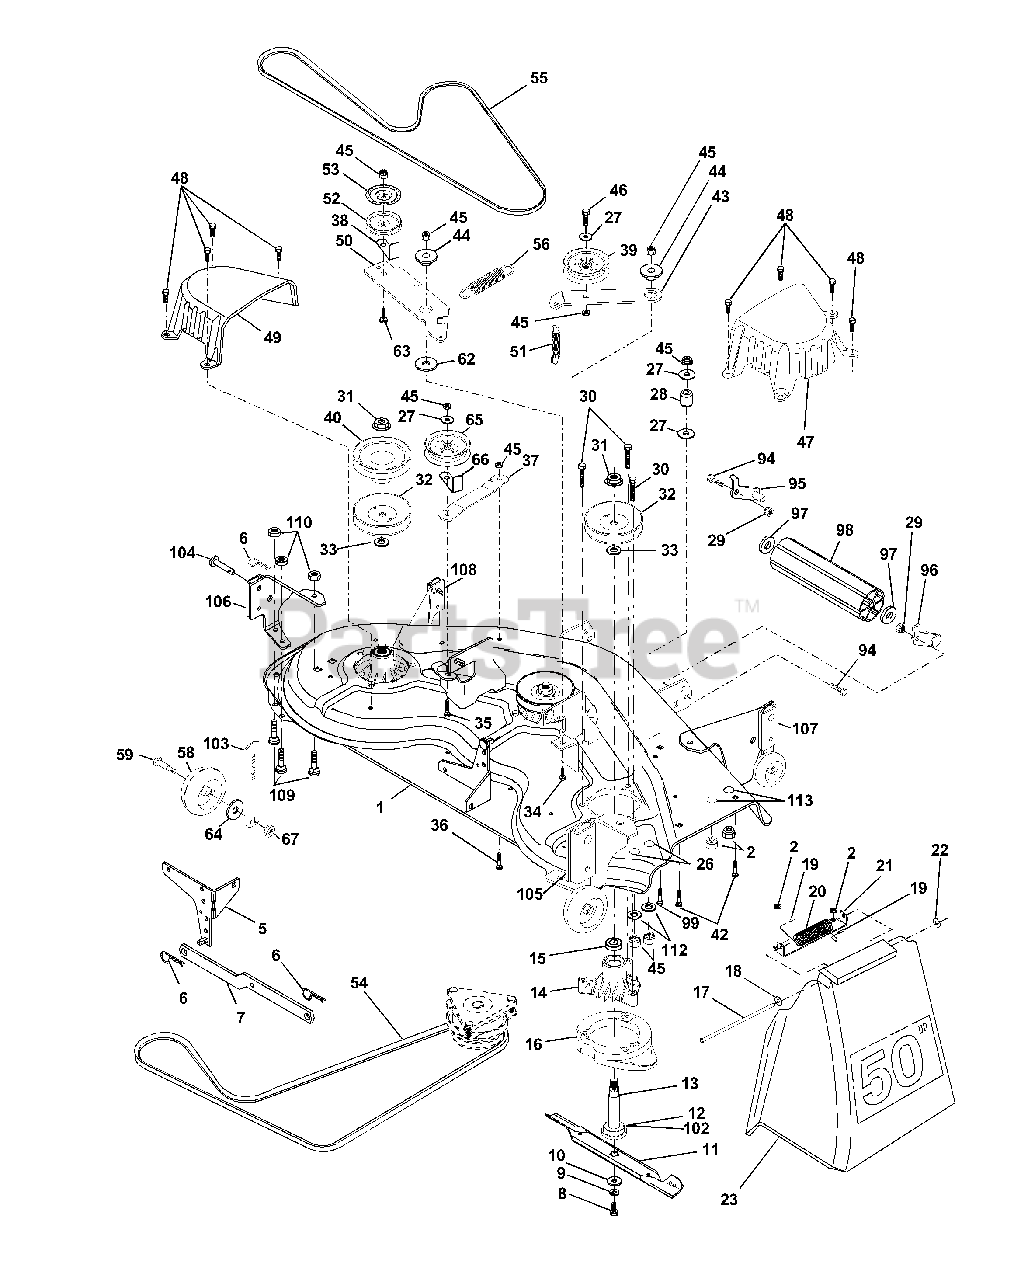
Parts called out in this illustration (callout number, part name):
1	Deck Asm., Mower 50"
2	Nut, Crownlock 5/16-18
5	Bracket Asm., Sway Bar
6	Retainer, Spring
7	Arm Suspension, Rear
8	Bolt 3/8-24 x 1.25 Gr. 8 Patched
9	Washer, Lock Hvy 3/8 Unplated
10	Washer, Hard Blade Mower Vented
11	Blade (3 Required)
12	Bearing, Ball #6204 (Mandrel)
13	Shaft Asm., W/Lower Brg
14	Housing, Mandrel 50" Vent
15	Bearing, Ball Mandrel
16	Stripper, Mower Vented
17	Rod, Hinge
18	Washer 11/32 x 5/8 x 16 Ga.
19	Cap Sleeve
20	Spring, Torison Delector
21	Bracket, Deflector
22	Nut, Push
23	Shield, Deflector Mower
25	Washer 11/32 x 3/4 x 16 Ga.
26	Bolt Rd Hd Sht Sqnk
27	Washer 13/32 x 13/16 x 16 Ga.
28	Spacer, Spring Stop Idler
29	Nut, Lock Hex W/Wsh 3/8-16 Unc
30	Screw Thd Rolling Washer Head
31	Nut, Flg Top Lock Cntr 9/16
32	Pulley, Mandrel
33	Washer, Spacer Mower Vented
34	Bolt, Carriage 3/8-16 x 1-1/4
35	Bolt, Carriage 3/8-16 x 2
36	Bolt, Carriage 3/8-16 x 1 Gr. 5
37	Stiffener, Arm Idler
38	Keeper, Belt Idler
39	Pulley, Idler Flat
40	Pulley, Driven
42	Bolt, Carriage 5/16-18 Unc x 3/4
43	Arm, Idler Secondary
44	Spacer, Retainer
45	Nut, Crownlock 3/8-16 Unc
46	Bolt, Fin Hex 3/8-16 Unc x 1-3/4
47	Cover, Mandrel RH
48	Screw, Thd Roll 1/4-20 x 5/8
49	Cover, Mandrel LH
50	Arm, Idler Primary
51	Spring, Secondary
52	Pulley, Idler V Groove
53	Shield, Idler
54	V-Belt, Mower Primary
55	V-Belt, Mower Secondary
56	Spring, Primary
58	Wheel, Gauge
59	Bolt, Shoulder
62	Washer Hardened
63	Bolt Carriage 3/8-16 x 1-1/2
64	Washer 3/8 x 7/8 x 14 Ga.
65	Pulley Idler Flat Mower
66	Keeper, Belt Idler 50" Vent
67	Nut, Center Lock 3/8-16
94	Bolt H 3/8-16 x 1
95	Bracket, Asm. Noseroller LH
96	Bracket, Asm. Noseroller RH
97	Washer 17/32 x 7/8 x 16 Ga.
98	Roller, Nose
99	Bolt, Carriage 3/8-16 x 1-3/4 Gr. 5
102	Washer Felt
103	Bar Adj. Gauge Wh.
104	Pin Head Rivot
105	Bracket Ga Wh Asm RH 50
106	Bracket Ga Wh Asm LH 50
107	Bracket Ga Wh Assy F RH 50
108	Bracket Ga Wh Assy F LH 50
109	Bolt Carraige 5/16- 18 x 5/8
110	Nut Crownlock 5/16-18
112	Washer 17/32 x 3/4 x 16 Ga.
113	Bolt Carriage 5/16-Unc 1/2
